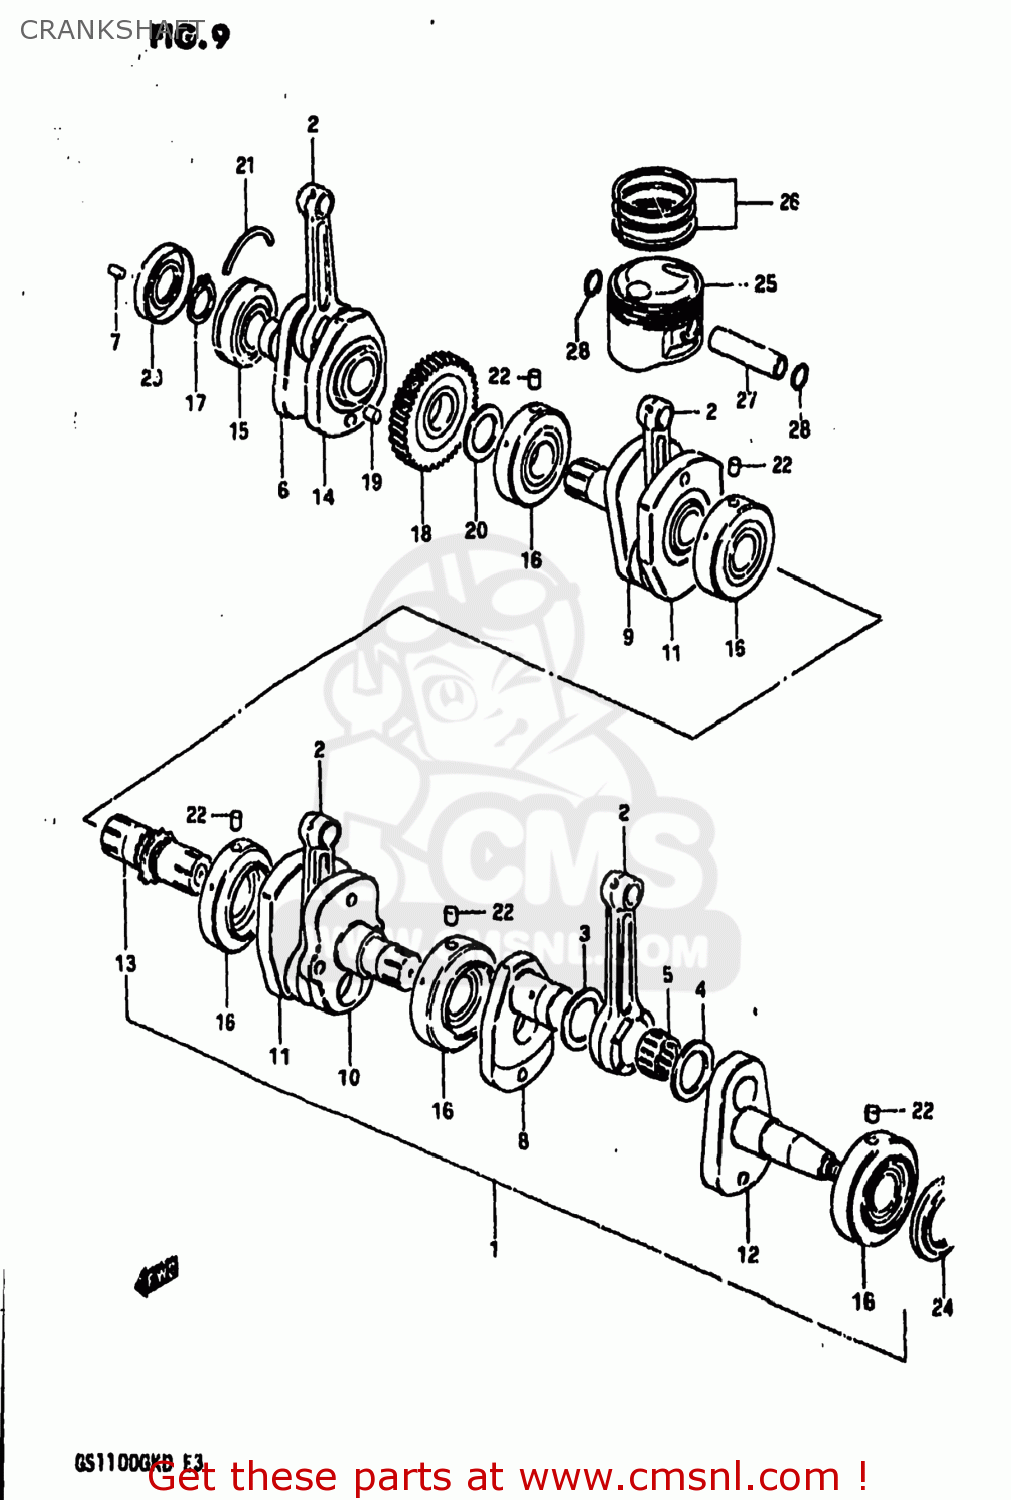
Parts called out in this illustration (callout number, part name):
1	CRANKSHAFT ASSEMBLY
2	ROD,CONNECTING
3	WASHER(31X48.5X1)
4	WASHER(31X48.5X2)
5	BEARING
6	CRANKSHAFT,RIGHT
7	PIN
8	WEB,CRANK
9	CRANKSHAFT,MIDDLE,RIGHT
10	CRANKSHAFT,MIDDLE,RIGHT
11	WEB,CRANK,MIDDLE
12	CRANKSHAFT,LEFT
13	SHAFT,TIMING CHAIN DRIVE
14	WEB,CRANK,RIGHT
15	BEARING(30X72X19)
16	BEARING
17	CIRCLIP,30MM
18	GEAR,PRIMARY DRIVE
19	PIN
20	WASHER
21	C RING
22	PIN
23	SEAL,OIL(30X72X11)
24	SEAL,OIL(47.3X60X6.5)
25	PISTON
26	RING SET,PISTON
27	PIN,PISTON
28	CIRCLIP
